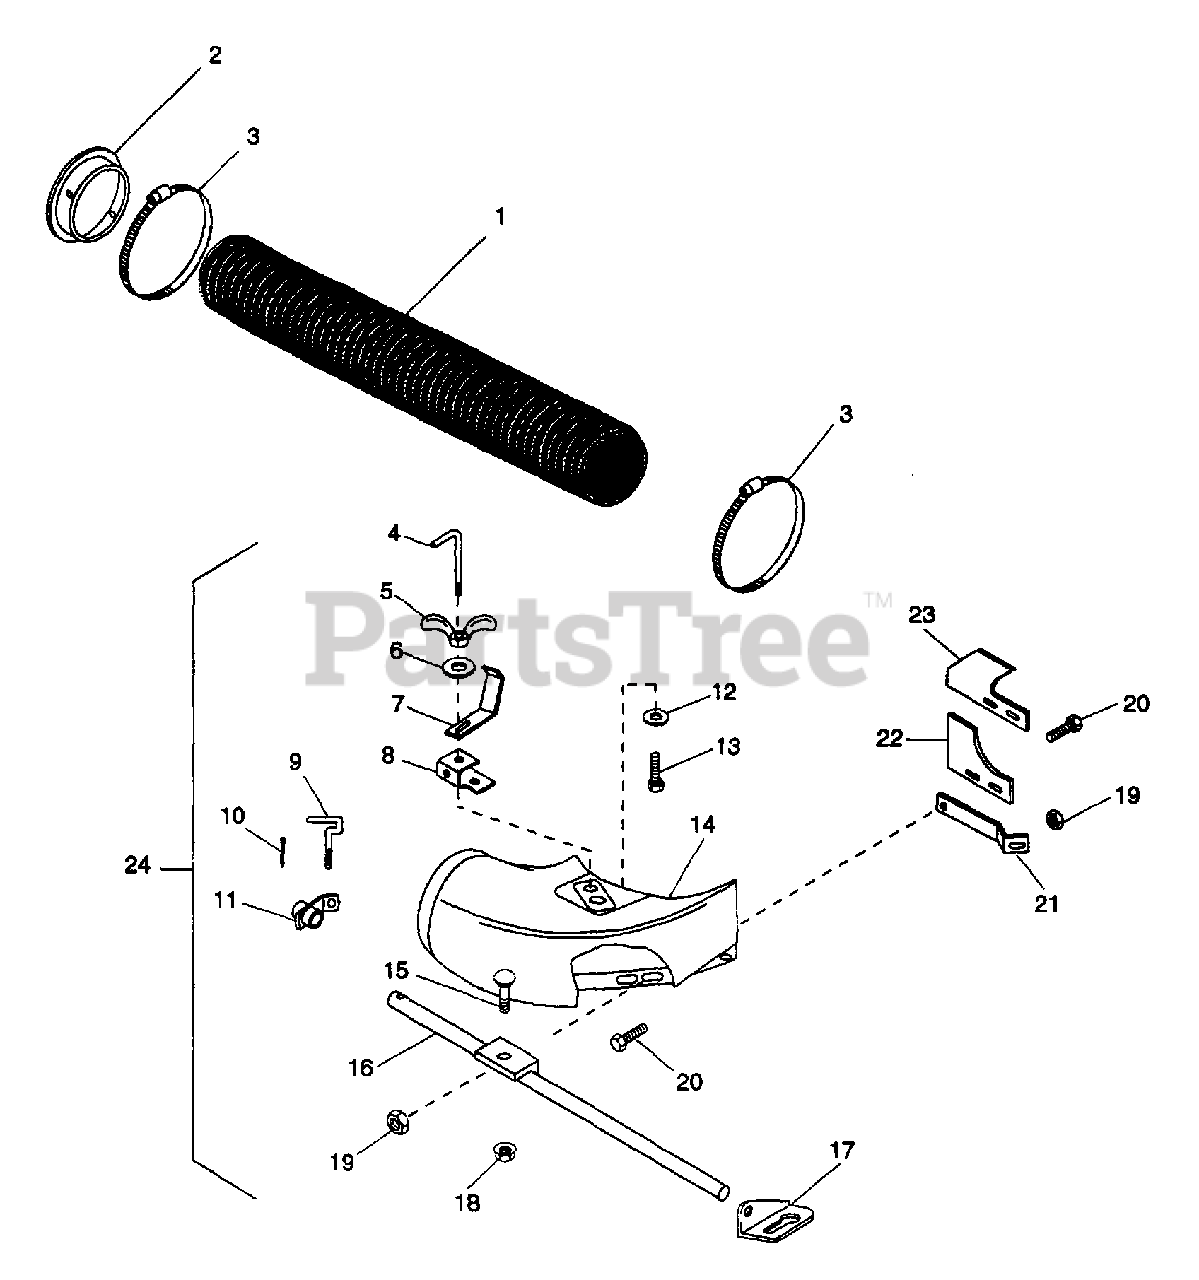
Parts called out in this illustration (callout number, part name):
1	HOSE 7X38
2	HOSE ADAPTER
3	CLAMP-HOSE WRM 2.13/8.62X.56
4	CLAMP SCREW
5	WING NUT, .312-18
6	WSHR-FL-STL .38X.875X.083 PL
7	DEFLECTOR STOP
8	COLLECTOR BOOT CLAMP
9	CLAMP SCREW
10	PIN-COTR .09X.75 PL
11	BOOT CLAMP
12	WSHR-FL-STL .625X1.250X.093
13	BLT-HEX .25-20X.38 PL GR2
15	BLT-RDHDSQNK .25-20X.50 SHT PL
16	BOOT BRACE
17	BOOT CLIP
18	NUT-LK-FLG .250-20 PL
19	NUT-LK-CTR .250-20 PL
20	BLT-HEX .25-20X.63 PL GR2
21	BRACKET - STOP
23	VAC PLATE
24	48 INCH BOOT ATTACHMENT RETROF
